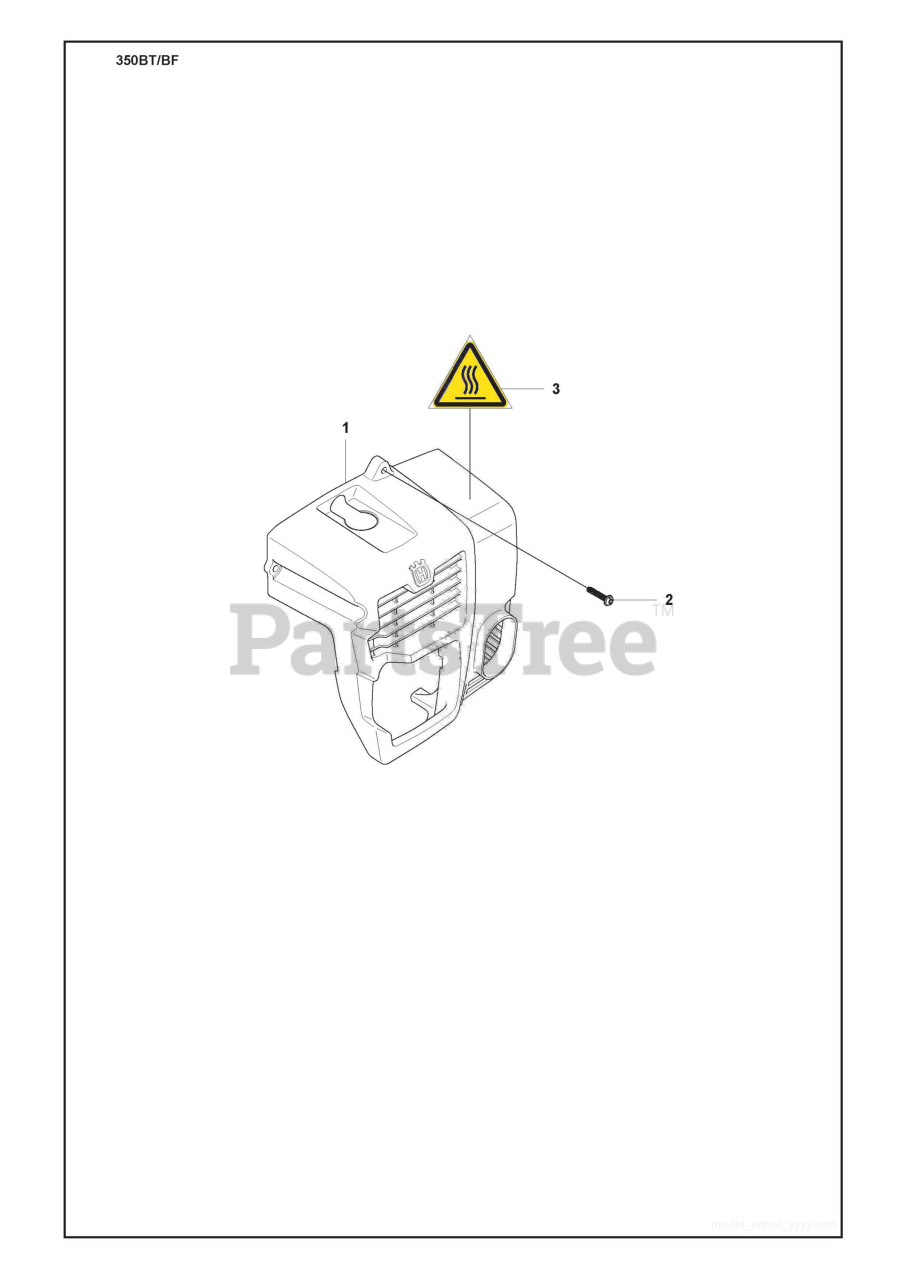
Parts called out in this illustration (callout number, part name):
1	CYLINDER COVER
2	SCREW
3	RP_LABEL, HOTMARK
